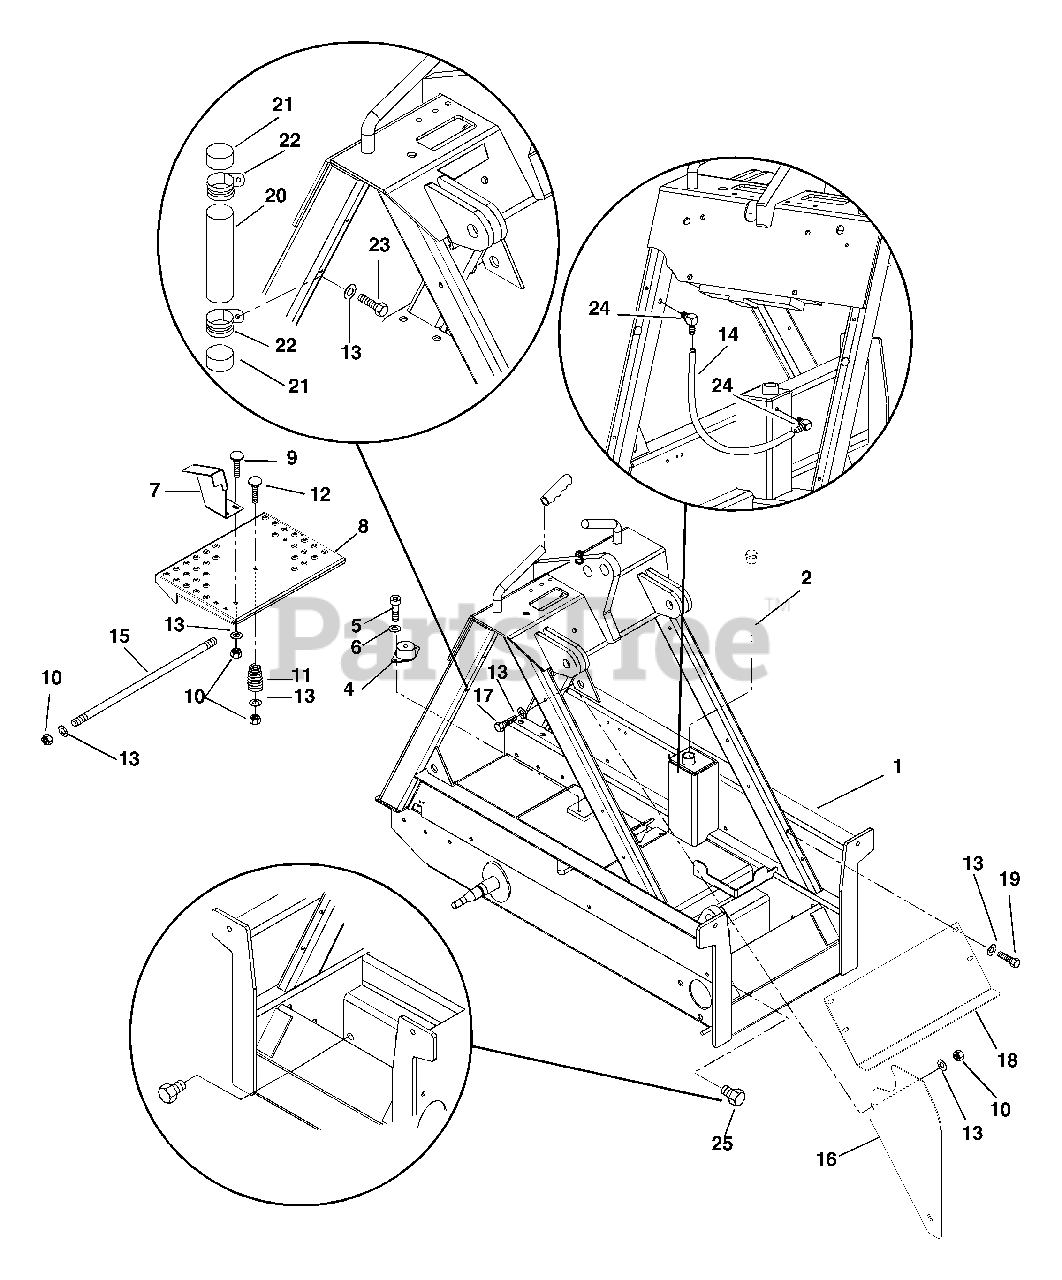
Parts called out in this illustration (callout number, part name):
2	Dipstick
3	Grip-Handle
4	Mount-Engine
5	Screw-Socket Head M8-1.25 x 12
6	Washer-Lock .31 x .078
7	Bracket-Hydraulic Stop
8	Grate-Floor Weldment
9	Bolt-Round Head Square Neck M8-1.25 x 20
10	Nut-Hex Locking Flange M8-1.25
11	Spring-Compression
12	Bolt-Round Head Square Neck M8-1.25 x 25
13	Washer-Flat-Steel .344 x .688 x .065
14	Line-Gas
15	Rod-Pivot
16	Guard-Pinch
17	Bolt-Hex M8-1.25 x 55
18	Plate-Inspection
19	Bolt-Hex M8 x 1.25 x 16
20	Tube-Instruction
21	End-Cap Instruction Tube
22	Clamp-2.00 Diameter with .406 Hole
23	Bolt-Hex M8 x1.25 x 16
24	Fitting-Barbed 90 Degree Elbow .125-27M x .25 I.D. Hose
25	Plug, Drain .75-14
